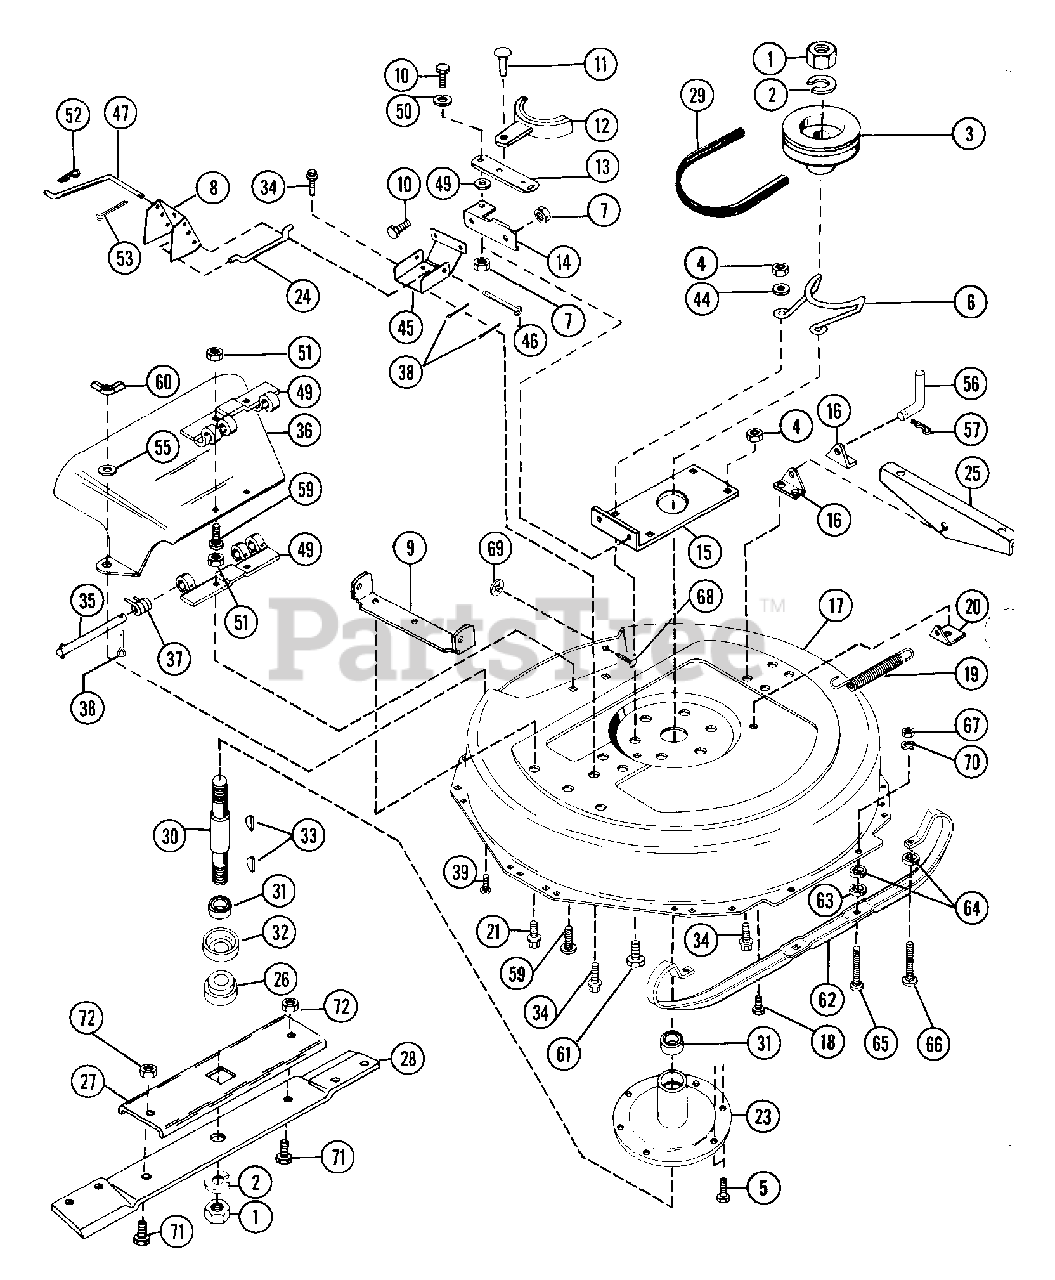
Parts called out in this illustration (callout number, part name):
1	NUT-JAM .75-10 PL
2	WSHR-LK .750X.188 MED PL
3	MOWER SHEAVE
4	NUT-LK-CTR .375-16 GR A PL
5	BLT-HEX .38-16X1.00 PL
6	MOWER BELT FINGER
7	NUT-LK .312-18 GR A PL
8	MOWER ENGAGING ARM
9	FRONT MOUNTING BRACKET
10	BLT-HEX .31-18X.63 PL GR 2
11	RVT .375 X 1.625 RH ST
12	BLADE BRAKE
13	MOWER BRAKE LEVER
14	BRAKE BRACKET
16	REAR MOUNTING BRACKET
17	28 IN MOWER PAN SERVICE ASSEMB
18	BLT-SERHFWH .25-20X.50 PL
19	SG-TENS .072X.51X5.31 WLD 25
20	BRAKE CLIP
21	BLT-SCRHFWH .38-16X.50 PL
23	SPINDLE HOUSING
26	RETAINER HUB
27	BLADE TRAY
28	MOWER BLADE 28
29	V-BELT
30	SPINDLE SHAFT
31	BRG-BALL .750X1.781X.61
32	BEARING SLINGER
33	KEY-WDRF .188X.75X.313 SAE 9
34	BLT-SERHFWH .31-18X.50 PL
35	CLEVIS PIN
36	DISCHARGE CHUTE
37	SG-TORS .090X.37X.63
38	PIN-COTR .09X.75 PL
39	BLT-RDHDSQNK .25-20X.75 GR5PL
44	WSHR-FL-STL .406X.865X.094 PL
45	PIVOT BRACKET
46	PIN-CLEV .309X3.50 SP
47	SWIVEL BRACKET
49	HINGE PLATE
51	NUT-LK-CTR .250-20 PL
52	MOWER ENGAGEMENT LINK
53	PIN-COTR .12X.75 PL
54	SPACER BUSHING .5 X .32 X .163
55	WSHR-FL-STL .328X1.0X.094
56	CLEVIS PIN
57	PIN-HAIR INT .08X.38X1.42 YWZC
58	MOWER BRAKE LINK
59	BLT-RDHDSQNK .25-20X.62 PL
60	NUT-WING .250-20
61	BLT-HEX .38-16X1.00 PL
62	28 IN ADJUSTABLE SKID
63	SPACER BUSHING .5 X .32 X .21
64	SPACER .328X.750X.375
65	BLT-RDHDSQNK .31-18X1.25 SHTPL
66	BLT-RDHDSQNK .31-18X1.75 SHTPL
67	NUT-HEX .312-18
68	BLT-RDHDSQNK .312-18X.62SHTPL
69	NUT-PUSH .312
70	WSHR-LK .312X.097 PL HVY
71	BLT-HEX .38-16X1.00 PL GR5
72	NUT-LK TOP .375-16 GR C YWZC
